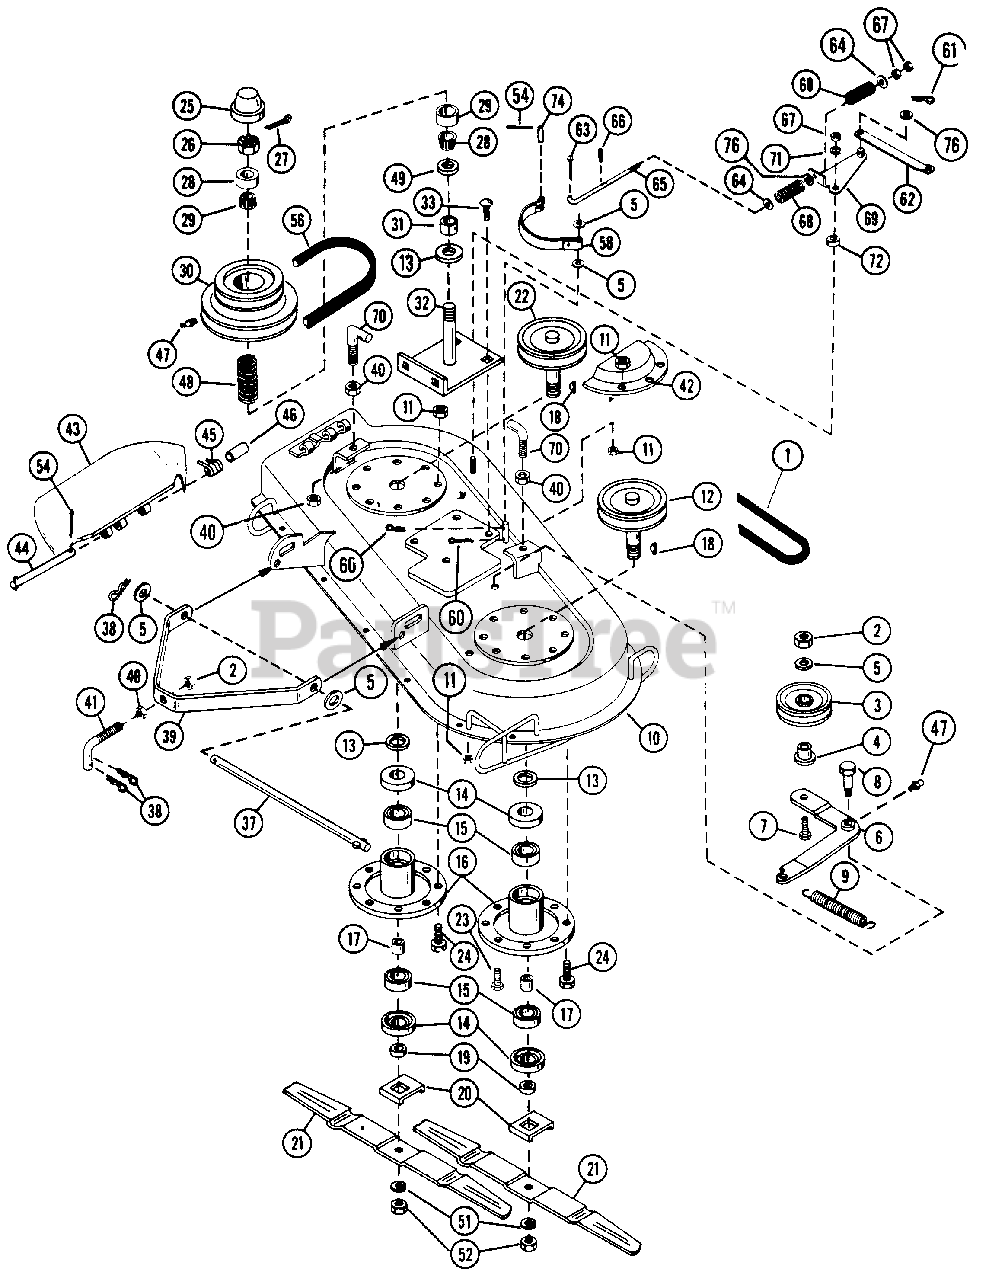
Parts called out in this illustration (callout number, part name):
1	BELT
2	NUT, LOCK 1/2-13
3	IDLER PULLEY
4	FLANGE BUSHING
5	WASHER, .505IDX.880ODX.072
6	IDLER ARM
7	CAP SCREW, 1/2-13X1.250
8	SHOULDER BOLT
9	SPRING
10	DECK(PAN)
11	NUT, LOCK 3/8-16
12	SHEAVE, 4"
13	WASHER, FLAT .938X1.750X.134
14	BEARING SLINGER
15	RADIAL BEARING
16	SPINDLE HOUSING
17	SPACER
18	KEY, NO. 9 WOODRUFF 3/16X3/4
19	RETAINER HUB
20	BLADE TRAY
21	MOWER BLADE
22	SHEAVE, 3-3/4"
23	BOLT, HEX 3/8-16X1.00
24	BOLT, HEX 3/8-16X.75
25	CAP
26	SLOTTED JAM NUT
27	COTTER PIN, 1/8"X1.25"
28	BEARING CUP
29	BEARING CONE
30	SHEAVE
31	SPACER
32	DRIVE PLATE
33	BOLT, CARRIAGE 3/8-16X.75
37	TOW PIN
38	HAIR PIN, 3/32X1-7/8 PL
39	MOWER STRAP
40	JAM NUT
41	TOW HOOK
42	COVER
43	CHUTE DEFLECTOR
44	HINGE PIN
45	SPRING TORSION
46	BUSHING
47	LUBE FITTING
48	SPRING, COMPRESSION
49	SEAL
51	LOCKWASHER, 3/4
52	JAM NUT, 3/4-10
54	COTTER PIN, 3/32X.75
56	MOWER BELT
58	BAND BRAKE
60	COTTER PIN 3/32X1
61	HAIR PIN, INTERNAL 3/32X1.27/64
62	LINK
63	COTTER PIN 1/16X.500
64	WASHER, FLAT .312X.734X.065
65	BRAKE ROD
66	ROLL PIN, 1/8X.75
67	NUT 5/16-18
68	SPRING
69	BRAKE LEVER
70	HANGER HOOK
71	LOCKWASHER
72	SPACER
74	PIN
76	WASHER
